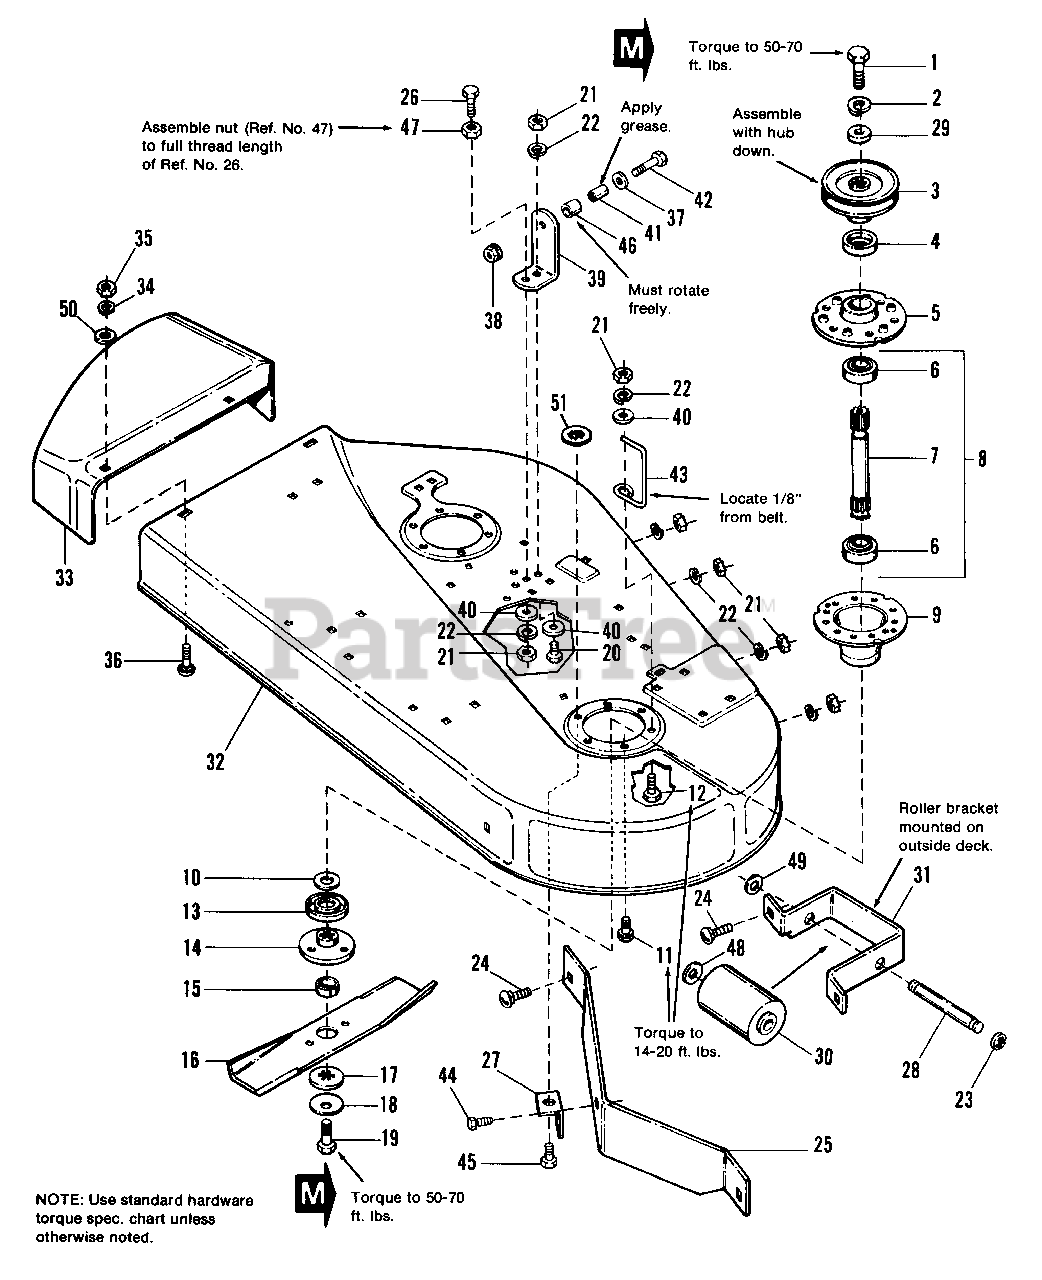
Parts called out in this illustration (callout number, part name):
1	CAPSCREW, Hex, 7/16-14 x 1-1/2
2	LOCKWASHER, 7/16
3	DRIVE PULLEY ASSY.
4	SHIELD, Bearing Upper, Arbor
5	HOUSING, Top
7	SHAFT (Incl. Ref. No.15)
8	SHAFT & BEARING ASSY. (Incl. Ref. Nos. 6, 7 & 15)
9	HOUSING, Bottom
10	WASHER, Shim
11	SCREW, Taptite, 5/16-18 x 5/8
12	SCREW, Taptite, 5/16-18 x 1
13	SHIELD, Lower Grass
14	ADAPTOR, Blade
15	COLLAR, Mower Arbor
17	WASHER, Spline
18	WASHER, Spring
19	CAPSCREW, Hex, 7/16-14 x 1
20	CAPSCREW, Hex, 5/16-18 x 1
21	NUT, Hex, 5/16-18
22	LOCKWASHER, 5/16
23	E-RING
24	BOLT, Carriage, 5/16-18 x 3/4
25	BAFFLE
26	CAPSCREW, Hex Hd., 5/16-18 x 1-1/2
27	BRACKET, Mower
28	SHAFT, Center Roller
29	WASHER, 29/64
30	ROLLER, Small
31	BRACKET, Center Roller
32	HOUSING, 36"
33	DEFLECTOR
34	LOCKWASHER, 3/8
35	NUT, Hex, 3/8-16
36	BOLT, Carriage, 3/8-16 x 3/4
37	WASHER, Plain
38	LOCKNUT, Hex, Flange, 3/8-16
39	SUPPORT, Up-Stop
40	WASHER, Plain, 5/16
42	CAPSCREW, Hex Head, 3/8-16 x 1-3/4
44	CAPSCREW, Hex Hd., 5/16-18 x 3/4
45	CAPSCREW, Hex Hd., 5/16-18 x 1-1/4
47	NUT, Hex, Jam, 5/16-18
48	WASHER, Spring
49	WASHER, Nylon
50	WASHER, Plain
51	PUSH NUT
